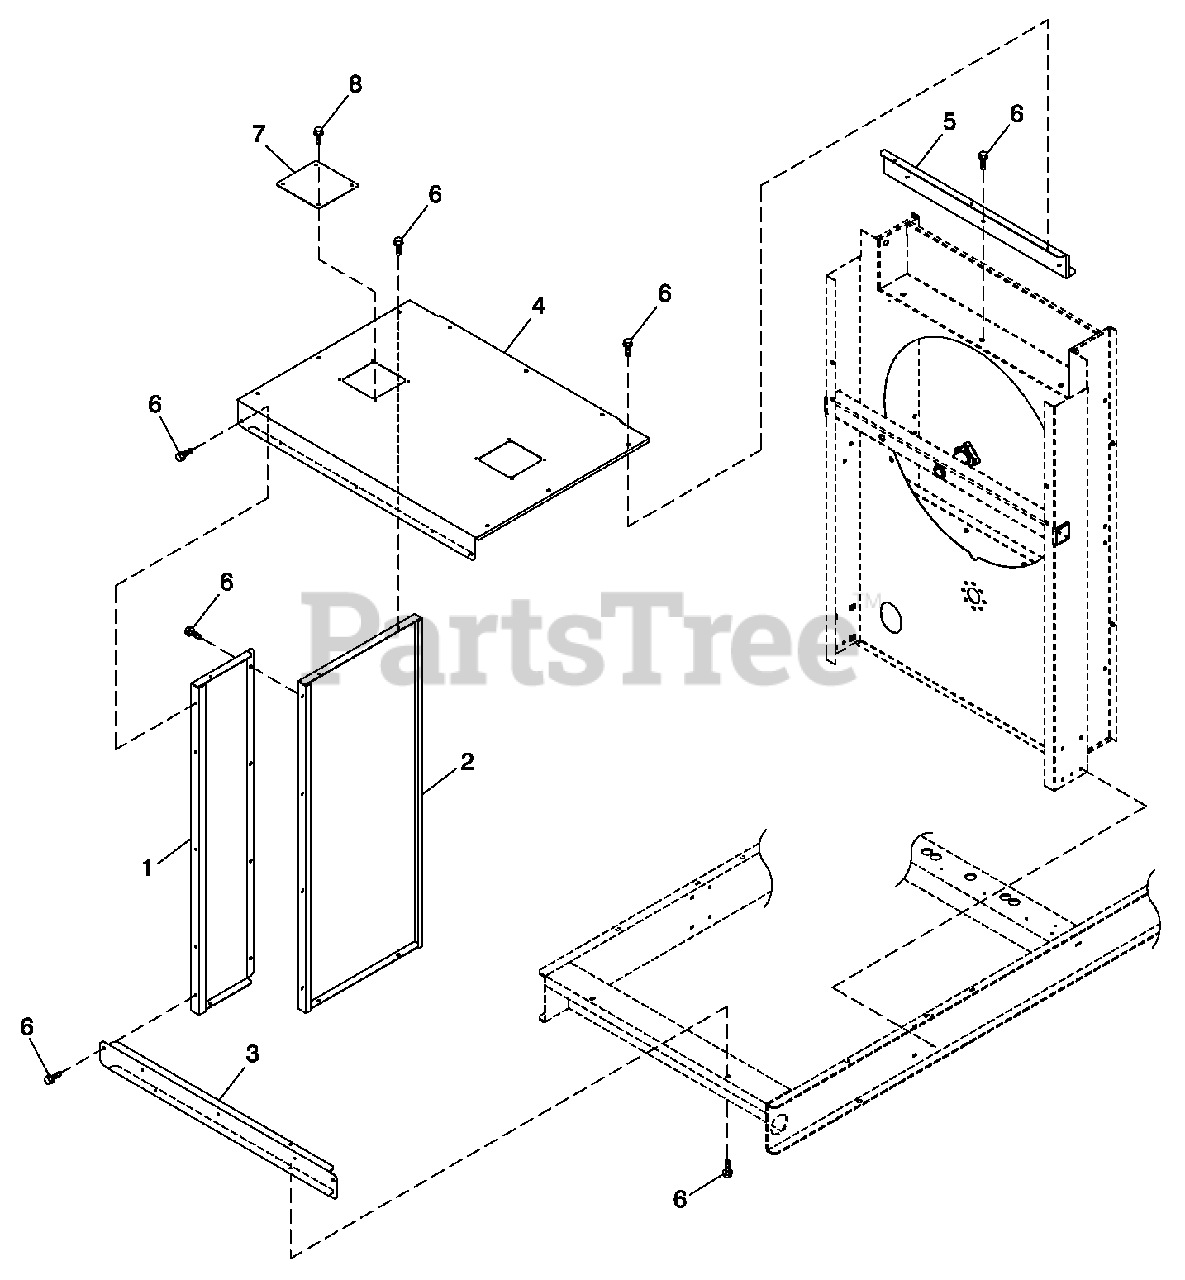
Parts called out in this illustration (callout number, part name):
1	WELDMENT RADIATOR SUPPORT C5
2	RADIATOR 680 X 680 X 70 CPL
3	V-BELT 31/64" X 62-3/8"
4	WASHER LOCK M10
5	SCREW HHC M10-1.5 X 30 C10.9
6	SCREW THF M6-1 X 16 N WA Z/JS
7	TAPE FOAM 1 X 1 (26.75" LG)
8	TANK COOLANT RECOVERY
9	PULLEY FAN V-GROOVE 9"
10	FAN 26" LH ROTATION
11	ARM BELT TENSIONER
12	SHOULDER BOLT 1/2 X 2-1/4"
13	SPRING TENSION CPL
14	PULLEY V-BELT 4" FLANGED
15	WASHER FLAT 3/8-M10 ZINC
16	SCREW HHC M8-1.25 X 45 C8.8
17	SCREW HHFC M6-1.0 X 20 G8.8
18	HUB FLEX PLATE
19	NUT HEX LOCK 5/16-24 NY INS
20	SCREW HHC M12-1.5 X 60 G8.8
21	DISK FLEX
22	COUPLING HUB FLEX (MACH)
23	CLAMP HOSE BAND 1/4
24	SCREW HHC 5/16-24 X 1.124
25	KEY WOODRUFF 4 X 19D
26	HOSE RADIATOR UPPER CPL
27	HOSE LOWER RAD CPL C5 6.8L
28	ASSY BRG/SHAFT CPL FANDRIVE
29	PULLEY 6.5" DIA MACHINED (6.8L 100KW)
30	SCREW HHC M10-1.5 X 30 G8.8
31	SCREW HHC 1/2-13X2" G8
32	WASHER FLAT 1/2 ZINC
33	WASHER LOCK 1/2
34	NUT HEX 1/2-13 STEEL
35	NUT HEX M6X 1.0 G8 YEL CHR
36	WASHER NYLON .50 X .87 X .06
37	CAP RADIATOR 13 PSI
38	BRACKET, SIGNAL CONDITIONER
39	WASHER FLAT 5/16-M8 ZINC
40	WASHER LOCK M8-5/16
41	SPACER .5 X 1.5 X .25 STL/ZINC
42	CLAMP HOSE #28 1.32-2.25
43	SCREW HHTT M4-0.7 X 8 BP
44	SPRING CLIP HOLDER .37-.62
45	CLAMP HOSE .38-.87
46	BARBED STR 3/8 NPTX3/8
47	HOSE DRAIN ASSY 28"
48	CAP HEX 1/4 NPT BRASS
49	BRACKET COOLANT TANK
50	WASHER FLAT 1/4-M6 ZINC
51	WASHER LOCK M6-1/4
52	SCREW HHC M6-1.0 X 20 G8.8
53	SHIELD RADIATOR
54	SCREW HHC M8-1.25 X 20 G8.8
55	WASHER LOCK M12
56	WASHER FLEX (THIN)
57	PROBE COOLANT LEVEL 3/8-18NPTF
58	BRACKET TENSIONER SPRING
59	HOSE 9/32 ID (43"LG)
60	NUT HEX LOCK M8-1.25 NY INS
61	BEARING SLEEVE 1/2/ X 3/4 X 1
62	SPACER CPL COOLING FAN 1/8"
63	SCREW HHC M10-1.5 X 20 C8.8
64	SCREW SHC M10-1.5 X 35 G12.9
